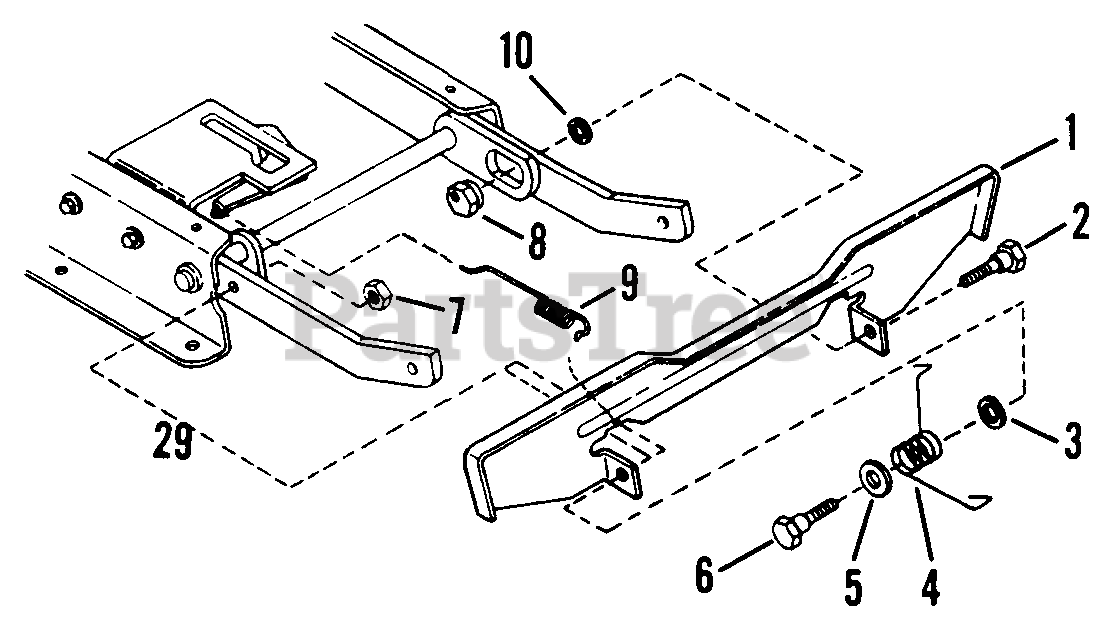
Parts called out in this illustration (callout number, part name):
1	PEDAL, Blade Stop Control
2	BOLT, 3/8-24 x 3/4" Shoulder
3	WASHER, 3/8" Flat
4	SPRING, Pedal
5	WASHER, 1/2 Flat
6	BOLT, 3/8-24 x 9/16" Shoulder
7	NUT, 3/8-24 Hex Lock
8	ECCENTRIC, Leveling
9	SPRING, Latching
10	WASHER, 3/8 Internal Tooth Lock
